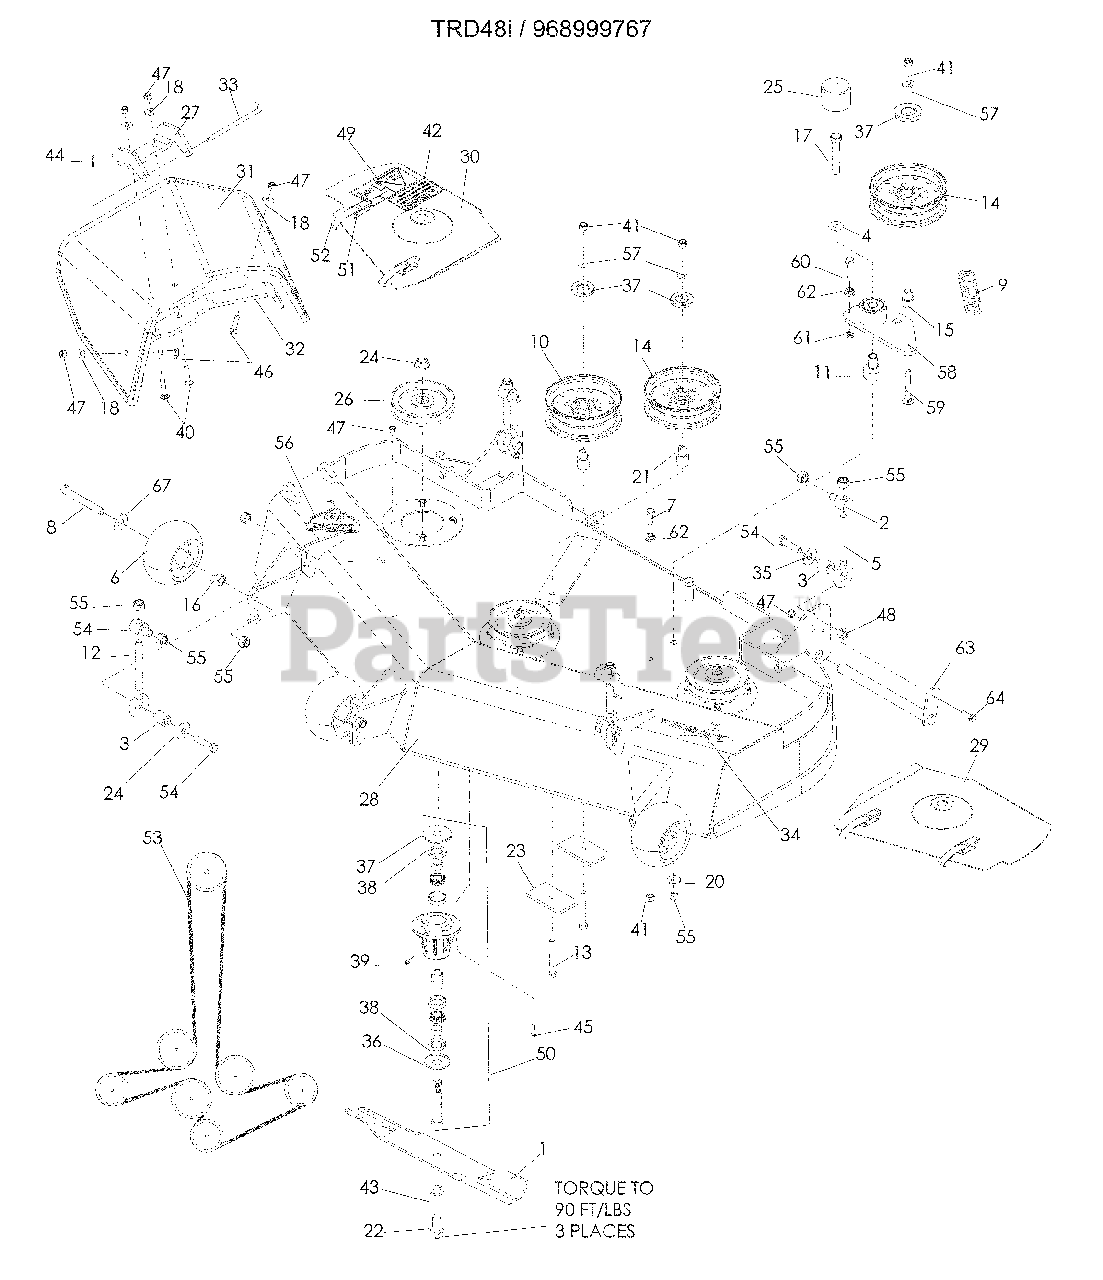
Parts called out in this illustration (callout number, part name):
1	BLADE 16¼
4	WASHER ½ BELLEVILLE
6	ROLLER, ANTI SCALP
7	HCS 3/8-16 x 1
8	HCS ½-13 x 4
9	SPRING, EXTENSION
10	PULLEY, IDLER
11	PIVOT, BEARING
12	EYE BOLT, ½-13 x 5.88
13	HCS 3/8-16 x 3
14	PULLEY, IDLER
15	BUSHING, IDLER
17	HCS ½-13 x 3
18	WASHER 5/16
19	DUST CAP, TOP
20	WASHER ½ SAE
21	BUSHING, IDLER
22	HCS 5/8-18 x 1¼
23	PAD
24	NUT ¾-16 FLANGE
25	CAP, VINYL
27	BRACKET, RUBBER CHUTE
28	DECK w/ DECALS
29	BELT SHIELD, RIGHT
30	BELT SHIELD, LEFT
31	DISCHARGE CHUTE
32	REINFORCEMENT, BRCKET
33	PIN, CLEVIS, 5/16
34	DECAL, TUNNEL RAM
36	DUST CAP, BOTTOM
37	SHIELD, DUST
38	SHAFT SEAL
39	GREASE POPPET
40	RHSNB 5/16-18 x 1½
41	NUT 3/8-16 NYLOC
42	DECAL, WARNING
43	LOCKWASHER 5/8
44	PIN COTTER, 1/8 x ¾
45	HCS 5/16-18 x 1¼
46	RHSNB 5/16-18 x 1¼
47	NUT 5/16-18 NYLOC
48	NUT 7/16-14 CNTRLK, GR A
49	DECAL, SEVERING
50	SPINDLE ASSEMBLY
52	DRAW LATCH
54	HCS 7/16-14 x 1¾
55	NUT ½-13 NYLOC
56	DECAL, CPSC
57	WASHER 3/8 THICK
58	ARM w/ BEARINGS, IDLER
59	RHSNB 3/8-16 x 2¾
60	HCS 3/8-16 x 1½ GR8
61	NUT 3/8-16 JAM
62	NUT 3/8-16 WHIZLK
64	HCS 5/16-18 x 1
